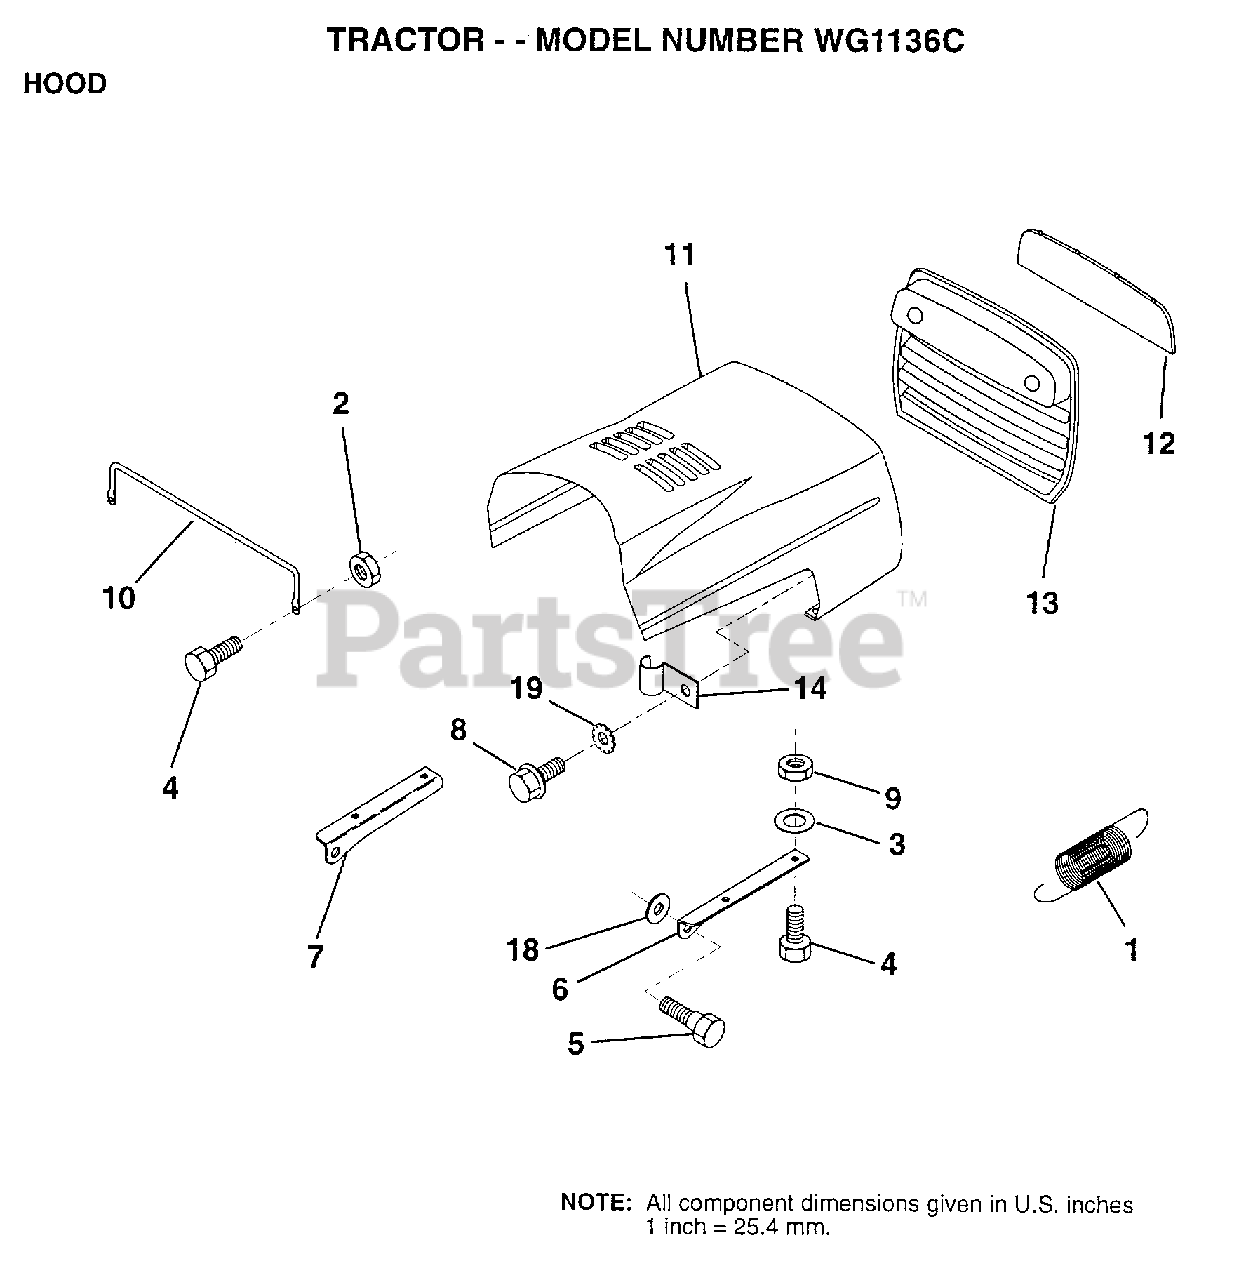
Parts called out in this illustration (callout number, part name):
1	EXT SPRING
2	NUT HXKEP 1/4X20
3	WASHER
5	BOLT.SHLD.5/16-18
6	BRKT HOOD RH
7	BRKT HOOD LH
8	SCREW SLTD HXHD
9	NUT
10	"BRACE,HOOD"
11	HOOD.IMPREG.MS550
12	LENS
13	GRILL
14	CLIP T
18	WASHER
19	LOCKWASHER GT
